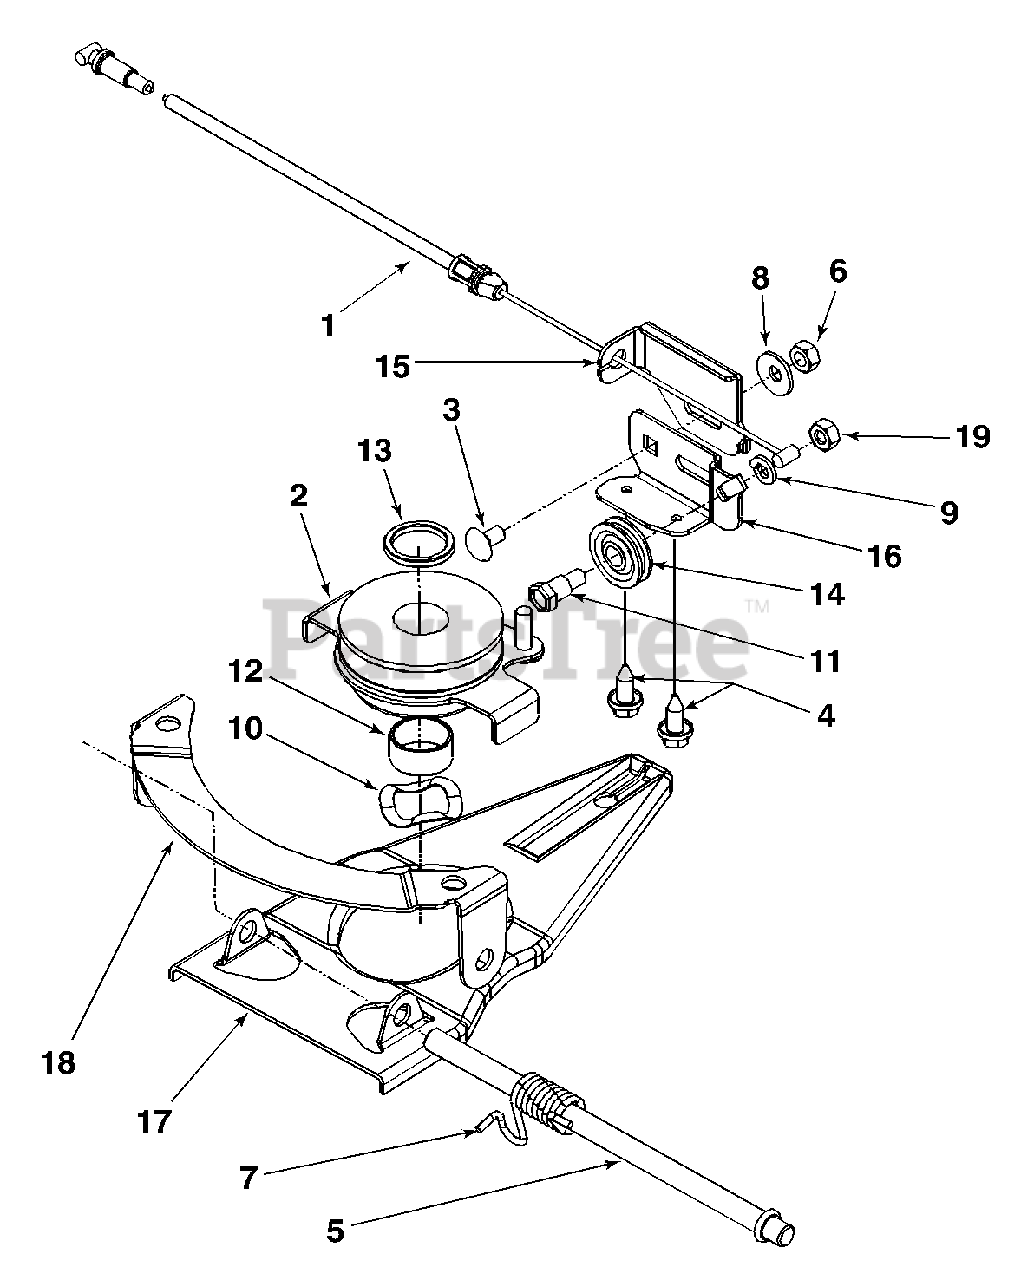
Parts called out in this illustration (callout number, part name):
1	6 Spd. Cable
2	Pulley Ass'y Mult - Spd.
3	Scr. 1/4-20 x .50 Carr.
4	Scr. AB Hex Hd. Wsh.
6	Nut 1/4-20
7	Torsion Spring LH
8	Bell Wash. .265 X .75 X .062
9	Lock Wash. 1/4 Reg Duty
10	Wave Wash. 1.38 x .88 x .029
11	Shld.Scr. .375 x 1/4 -14AB
12	Slev Spacer.88 ID 1.00 OD x.48
13	Slev Spacer .88 ID x 1.13 ID x .12
14	Roller Cable
15	6 Spd. Cable Adj. Bracket
16	6 Spd. Cable Mt. Bracket
19	Hex Nut 1/4-28
